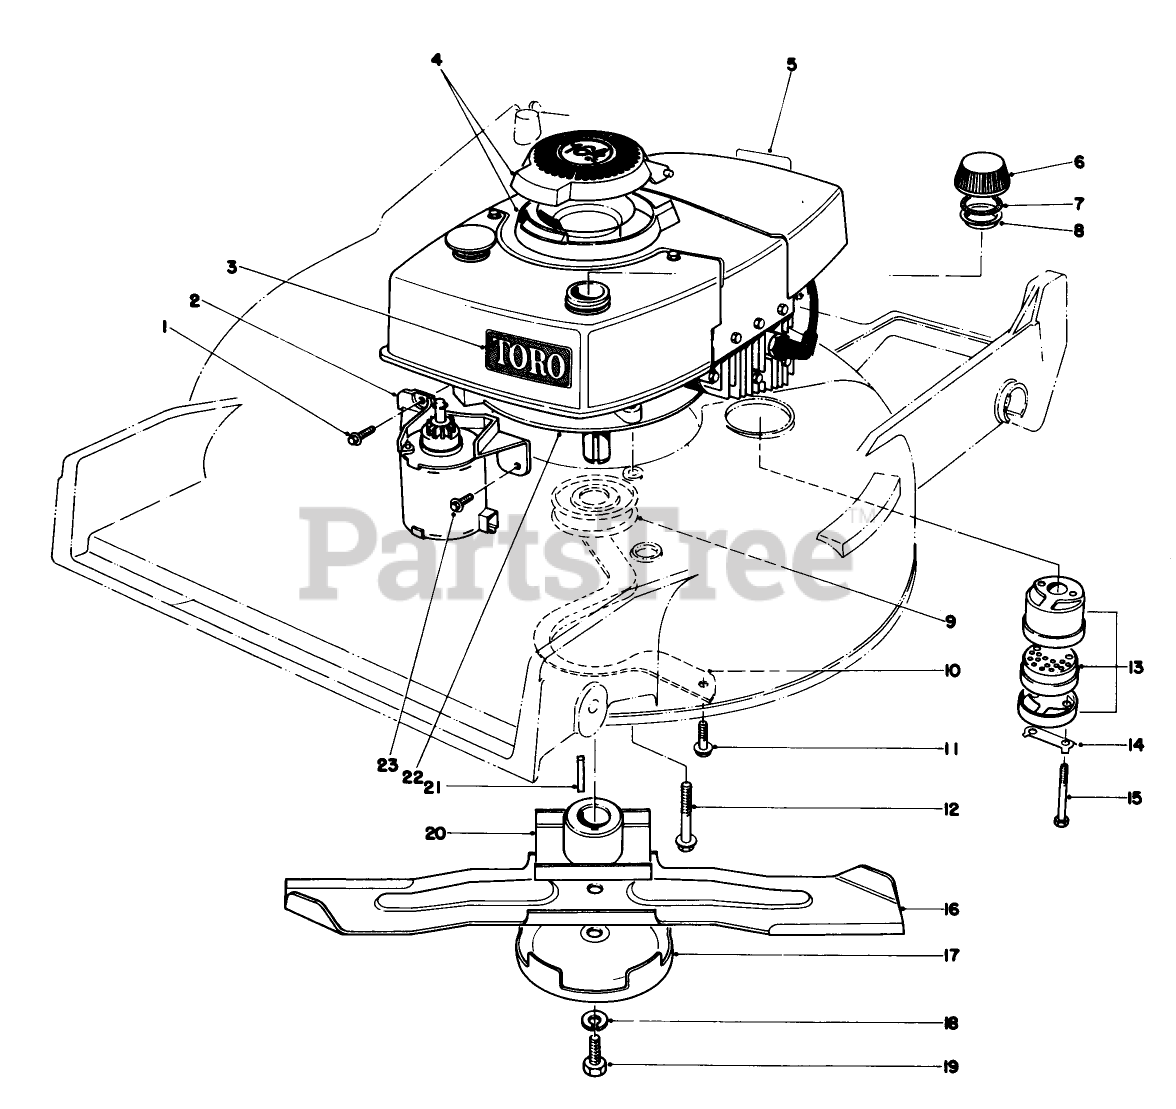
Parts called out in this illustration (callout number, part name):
7	GASKET
13	MUFFLER ASM
14	CLIP - LOCKING
15	SCREW-HH
18	WASHER-LOCK
19	BLADE SCREW
21	KEY-SQUARE
22	Engine
23	SCREW
